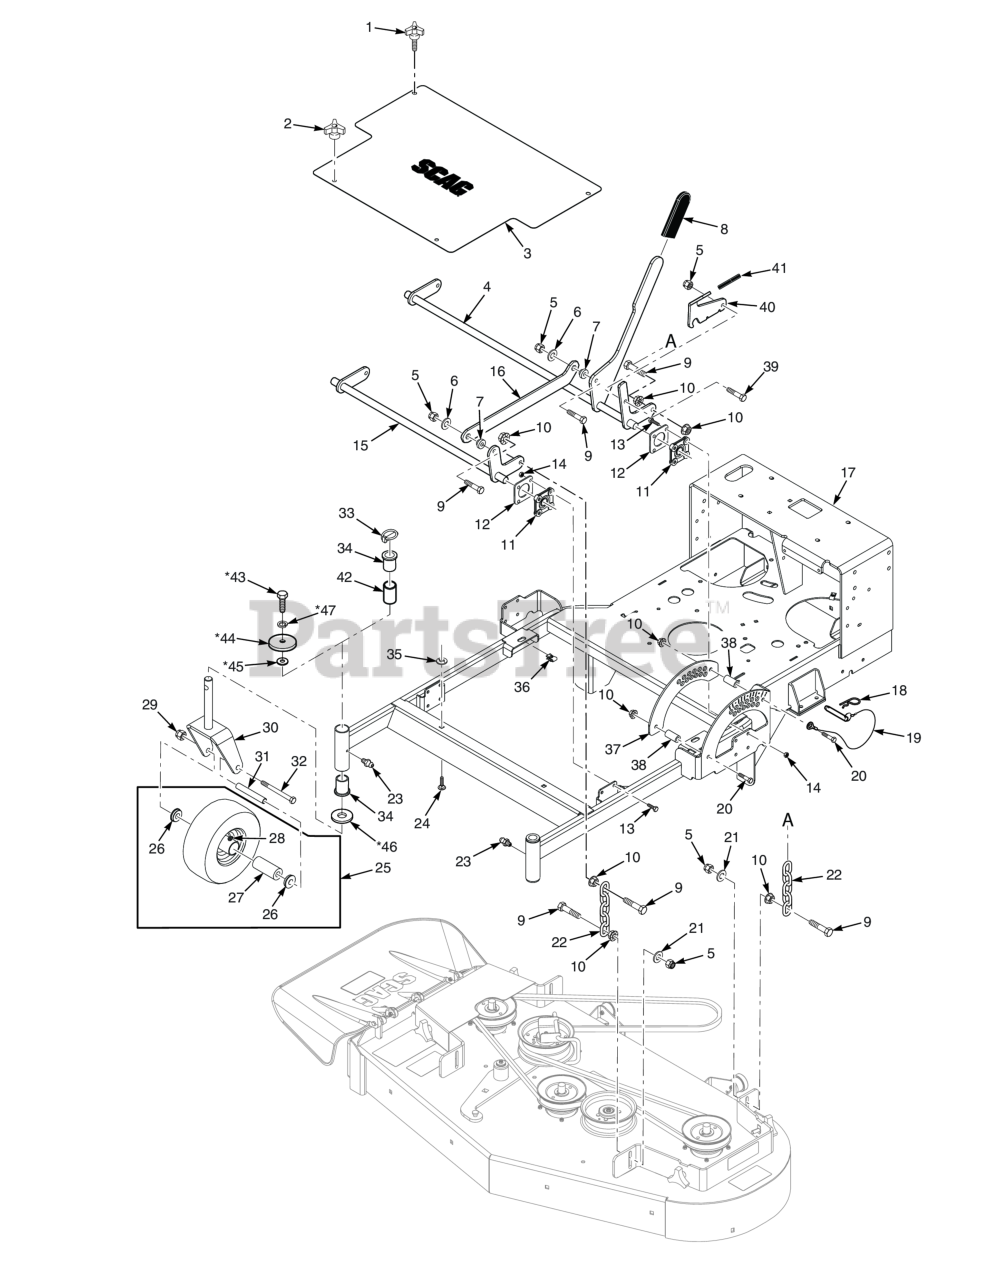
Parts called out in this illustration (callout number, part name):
1	Knob, w/stud 3/8-16 x 1-1/4"
2	Wing Nut, 3/8-16 (Small) Top side
3	Belt Cover w/Decals
4	Deck Bellcrank Assy.
5	HEX NUT, ELASTIC STOP LOCK, 3/8-16
6	Flatwasher, 3/8" Special (.391 x .938 x .105)
7	BUSHING, SPEED ADJUSTMENT LEVER
8	Grip, Deck Lift
9	Bolt, Hex Head, 3/8-16 x 1-1/2"
10	NUT, 3/8-16 SERRATED FLANGE HEX HEAD
11	Bearing, Deck Lift - 48V & 52V
12	Reinforcement, Bearing - 48V & 52V
13	Cpscrw, 5/16-18 x 1"Serrated Flange Hex Head
14	Nut, Center Lock, 5/16-18(32)
15	Deck Lift Weldment, Front
16	Link, Decklift
17	Frame w/Decals (SWZT 36 & 48)
18	Hair Pin Cotter, .177" x 3-1/4"
19	Lanyard, Deck Height Pin Assembly
20	Capscrew, Hex Head 3/8-16 x 2-1/2"
21	Flatwasher, 3/8" Special (.391 x .938 x .105)
22	Chain, Deck Lift
23	GREASE FITTING, STR. 1/4-28 SELF TAP.
24	Carriage Bolt, 3/8-16 x 1.0"
25	Flat Free Tire Assy.
26	Retainer, Bearing, Caster Wheel
27	Roller Bearing, .625 x 3-1/4"
28	GREASE FITTING, 45 DEGREE 1/4-28
29	HEX LOCKNUT, ELASTIC STOP, 1/2-13
30	Caster Yoke Weldment
31	SLEEVE, CASTER WHEEL BEARING
32	Bolt, Hex Head 1/2-13 x 5-1/2" (Three Weights Installed)
33	Quick Pin, .438" Dia.
34	Bronze Bushing, 7/8 ID x 1.0 Flanged
35	Nut, Push-On - 3/8" Dia.
36	U-Nut, 3/8-16 (short)
37	Bracket, Deck Height
38	Spacer
39	Bolt, Hex Head, 3/8-16 x 1 Gr. 5
40	Lever Assembly, Deck Latch
41	Grip, Deck Transport Lock
42	Spacer, Caster Bearing
43	Bolt, Hex Head, 3/8-16 x 1 Gr. 5
44	Flatwasher, 3/8-.406 x 2.25" x .1875
45	Flatwasher, 7/16" (.500 x 1.25 x .083")
46	Spacer, Yoke
47	Lockwasher, 3/8" Spring, Kawasaki FX / FS
